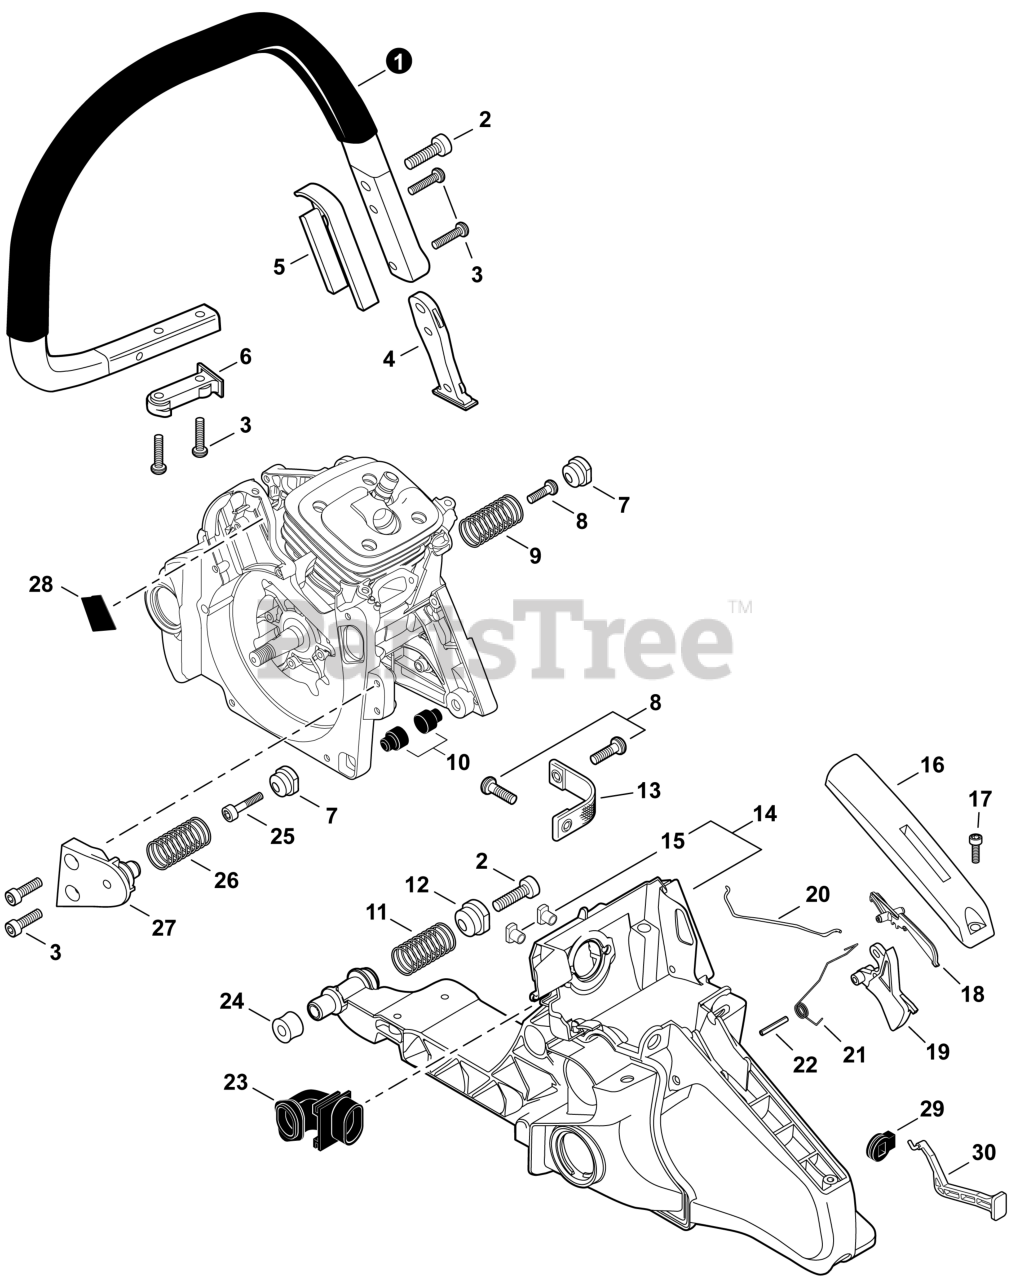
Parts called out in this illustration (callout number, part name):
1	HANDLE, FRONT
2	BOLT, TORX 6x20
3	BOLT, TORX 5x20
4	MOUNT, HANDLE
5	HOLDER, SPRING
6	MOUNT, HANDLE
7	HOLDER, SPRING 14.4
8	BOLT, TORX 5x16
9	SPRING, COMPRESSION 17x38.4x2.6
10	CUSHION
11	SPRING, COMPRESSION 20x40x3.3
12	HOLDER, SPRING 17
13	STRAP, SAFETY
14	HANDLE, REAR
15	NUT M5
16	COVER, HANDLE
17	BOLT, TORX 4x12
18	LEVER, THROTTLE LOCKOUT
19	TRIGGER, THROTTLE
20	ROD, THROTTLE
21	SPRING, TORSION
22	PIN, SPRING 4x25 SUS
23	PIPE, AIR INTAKE
24	CUSHION 10
25	BOLT, TORX 5x25
26	SPRING, COMPRESSION 17x36.7x2.6
27	HOLDER, SPRING
28	CUSHION
29	GROMMET, CHOKE
30	ROD, CHOKE
